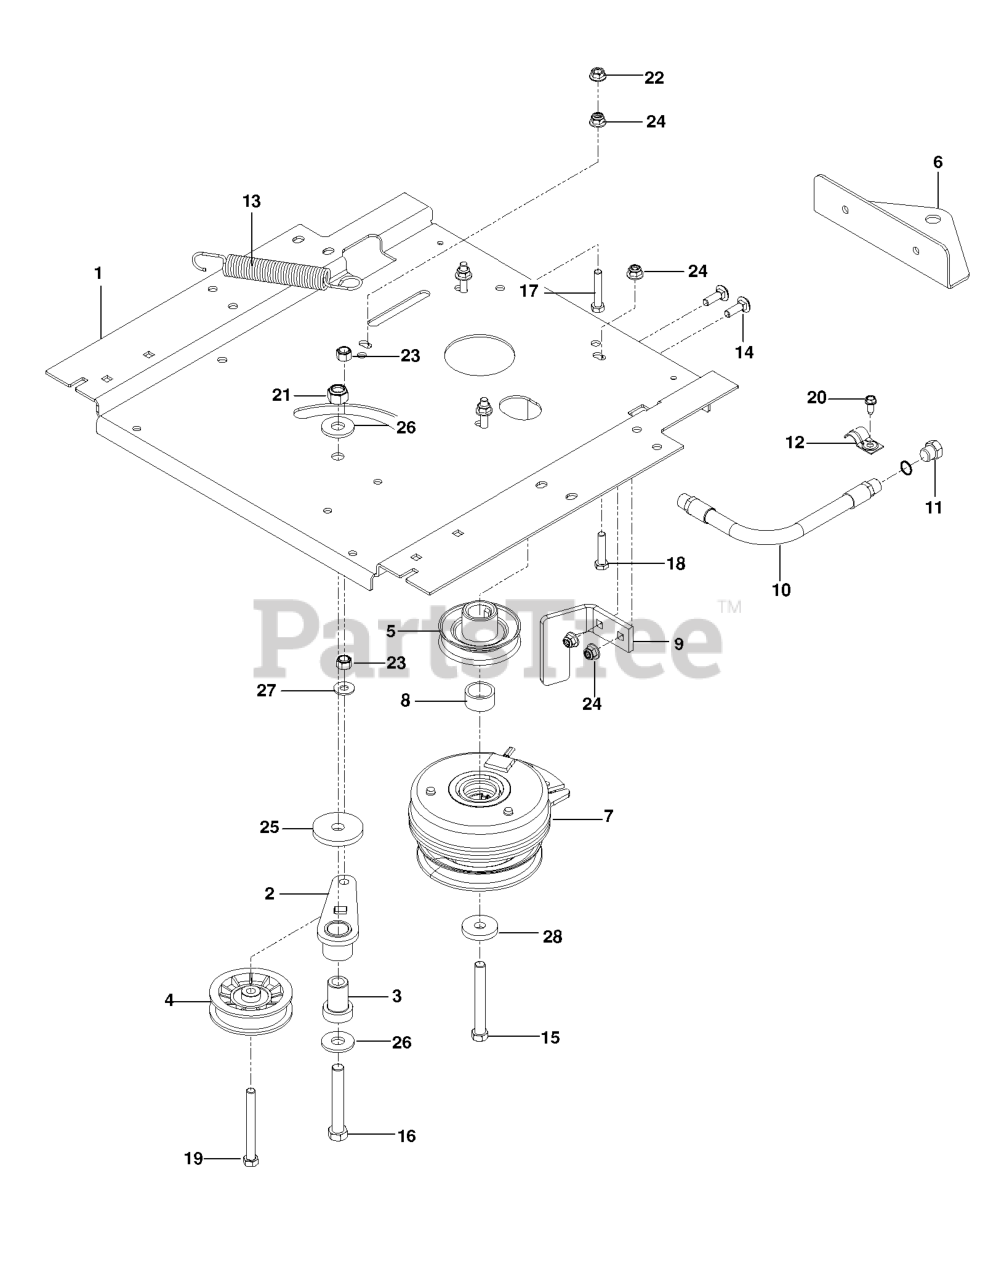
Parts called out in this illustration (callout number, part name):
1	PLATE, ENGINE BLK
2	RP.IDLER ARM WELDMENT
3	IDLER SPINDLE
4	PULLEY, IDLER RAKE & ZTR
5	PULLEY, ENGINE
6	HITCH, BLACK
7	CLUTCH.105.FT-LBS
8	T & B SPACER
9	STOP, CLUTCH, BLACK
10	HOSE.ASSEMBLY.OIL.DRAIN
11	PLUG OIL DRAIN
13	SPRING, DECK DRIVE
14	RHSNB 5/16C X 1
15	HCS 7/16-20X3-1/2 GR 5 ZN
16	HCS 1/2C X 3 1/4
17	HCS 5/16C X 1 3/4
18	CAPSCREW 5/16 X 1/1/2 HEX HEAD
19	HCS 3/8-16X3 1/2 GR5
20	SCREW 1/4 X 5/8
21	NUT.LK.W/WSH.1/2.
22	NUT 5/16C WHIZ
23	NUT 3/8-16 NYLOC
24	5/16-18 NYLOC FLANGE NUT
25	HEAVY WASHER
26	WASH USS FLAT 1/2
27	WASHER.5/16.FLAT.STE.STD.
28	CLUTCH, WASHER
